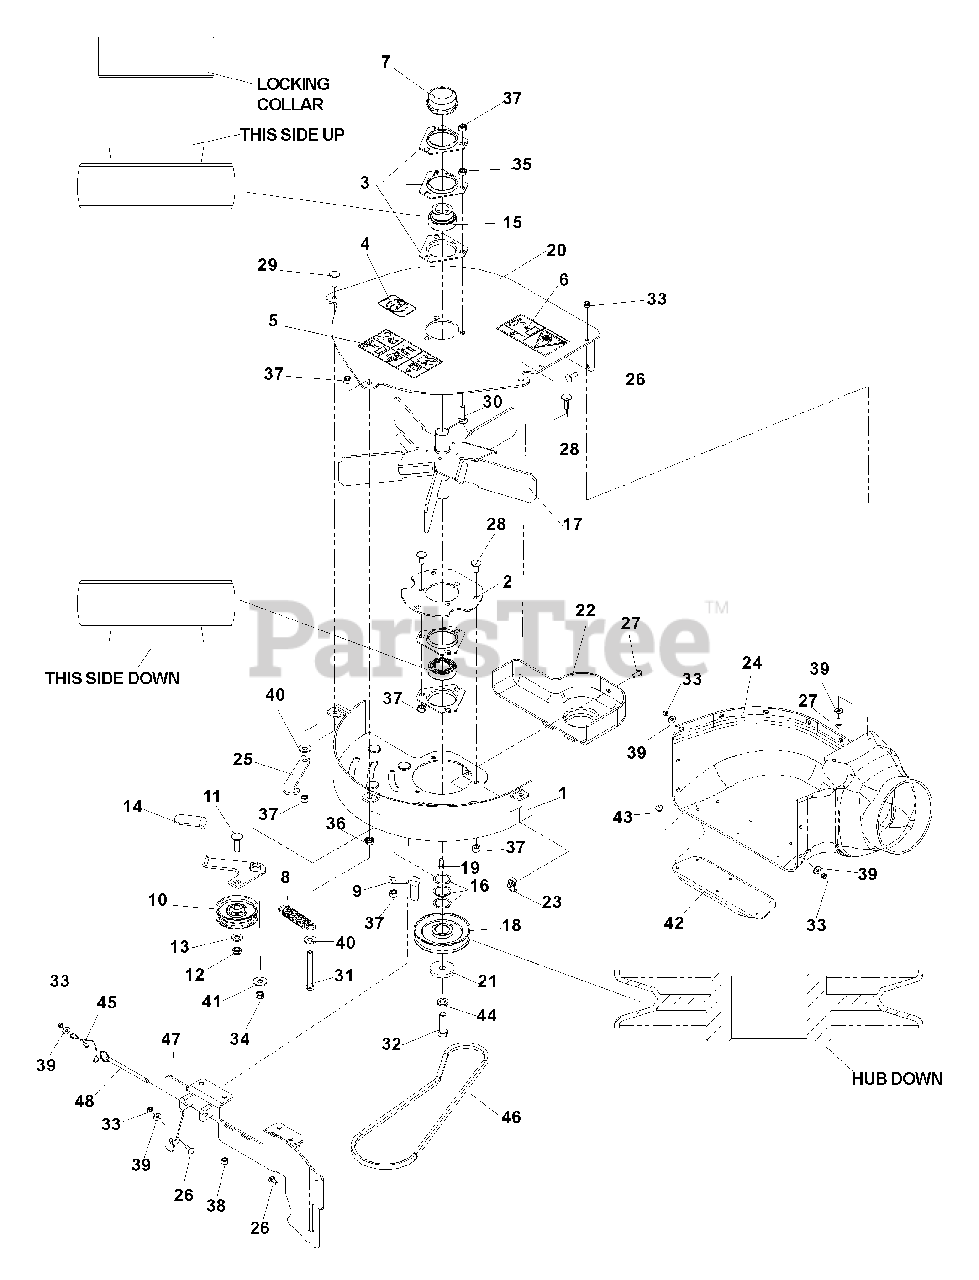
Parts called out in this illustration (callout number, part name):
1	FLOOR WELDMENT
2	BEARING PLATE
4	DECAL, NO STEP
5	DECAL, WARNING
6	DECAL, SEVERING
7	GREASE CAP
9	BELT GUIDE
11	RHSNB, 3/8 -16 x 1 1/2,
12	NUT, 3/8 -16, JAM NYLOC
13	WASHER, 3/8 , SAE
16	BUSHING, MACHINE, 18 GA
17	FAN WELDMENT
18	SHEAVE, 4"
21	WASHER, HEAVY
22	PULLEY SHIELD
23	RETAINER, 1/4C, "U" TYPE
24	BLOWER HOUSING
25	KEEPER, IDLER
26	RHSNB, 1/4 -20 x 3/4, GR2
27	SCREW, 1/4 -20 x 5/8 SKT HD
28	RHSNB, 5/16 x 3/4
29	RHSNB, 5/16 -18 x 1,
30	RHSNB, 5/16C x 1 1/4
31	HCS, 5/16 -18 x 2 3/4,
32	HCS, 7/16 -20 x 1 1/2,
33	NUT, 1/4C, THIN NYLOC
34	NUT, 5/16C, CENTERLOCK
35	NUT, 5/16 C
36	NUT, 5/16 C
37	NUT, 5/16 C, NYLOC
38	NUT, 3/8C, NYLOC
39	WASHER, 1/4
40	WASHER, 5/16
41	WASHER, 3/8
42	BLOWER SUPPORT
44	LOCKWASHER, 7/16
47	BLOWER DECK PLATE, 72
